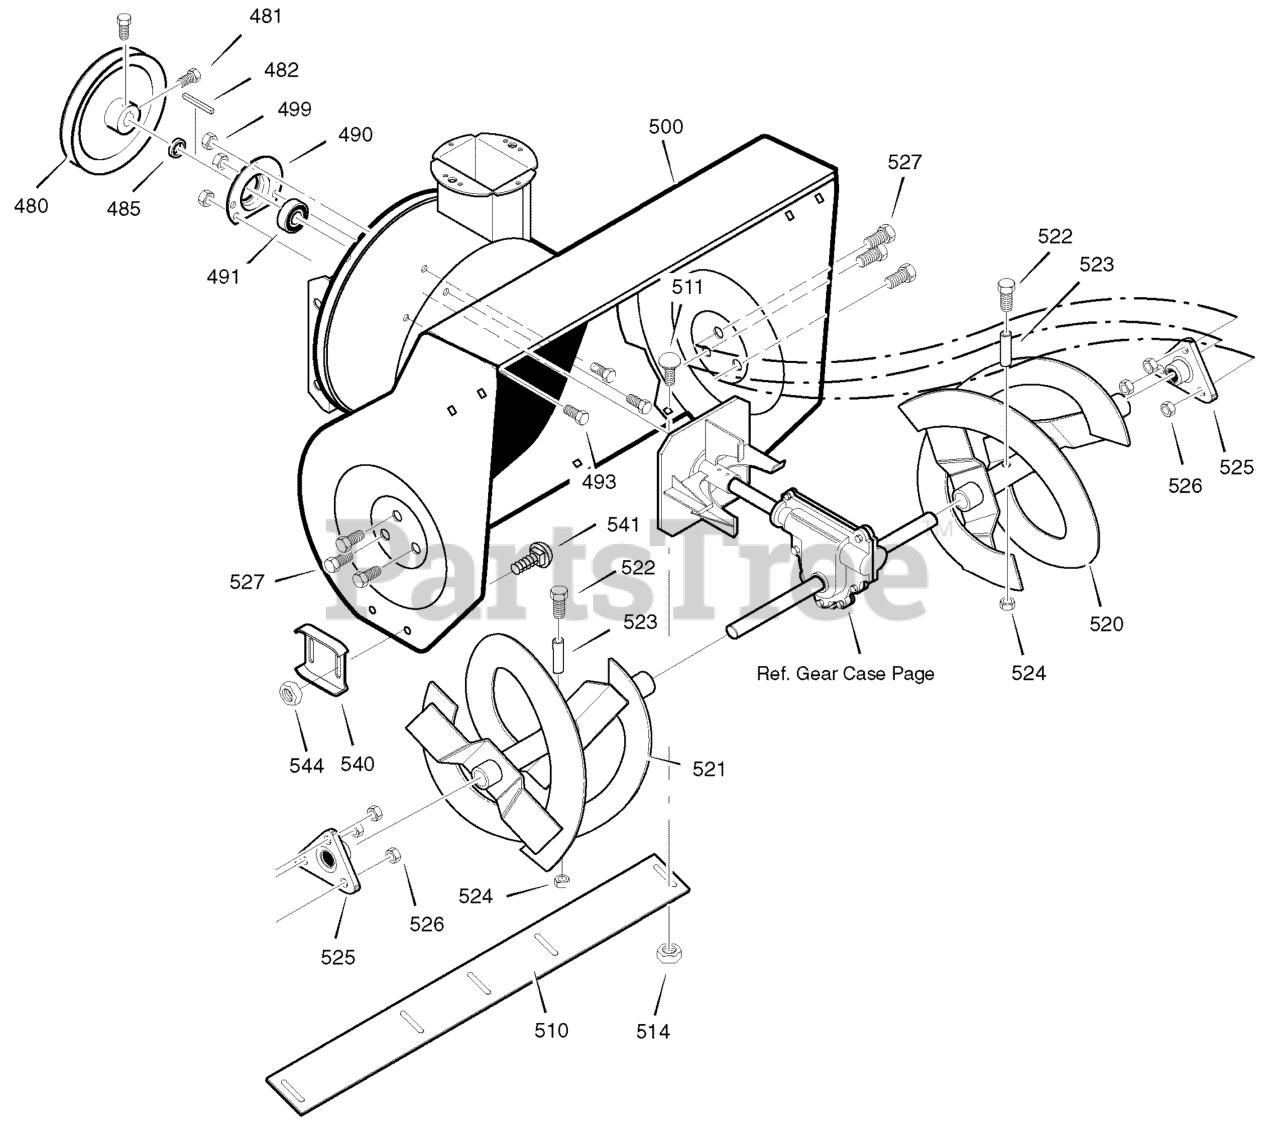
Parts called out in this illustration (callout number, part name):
480	PULLEY, 4L 6.12X .67
481	SCREW, 5/16-18 x 0.63
482	KEY, SQUARE 3/16 X 3/4
485	SPACER, FRICTION PULLEY
490	RETAINER, BALL BRNG
491	BEARING, BALL
493	BOLT, HEX 5/16-18X .50
499	NUT, 5/16-18 HEXWDFLLK
500	HOUSING, ASSY
510	BLADE, SCRAPER 24"
511	BOLT, 1/4-20X.75
514	NUT, 1/4-20
520	AUGER, ASSY, LH
521	AUGER, ASSY, RH
522	SCREW, 1/4-20X1.75
523	SPACER, SLEEVE
524	NUT, 1/4-20
525	BEARING,FLANGE
526	NUT, 5/16-18
527	SCREW, 5/16-18 x 0.75
540	SKID, HEIGHT ADJUST
541	BOLT, 5/16-18 X .75
544	NUT, 5/16-18
